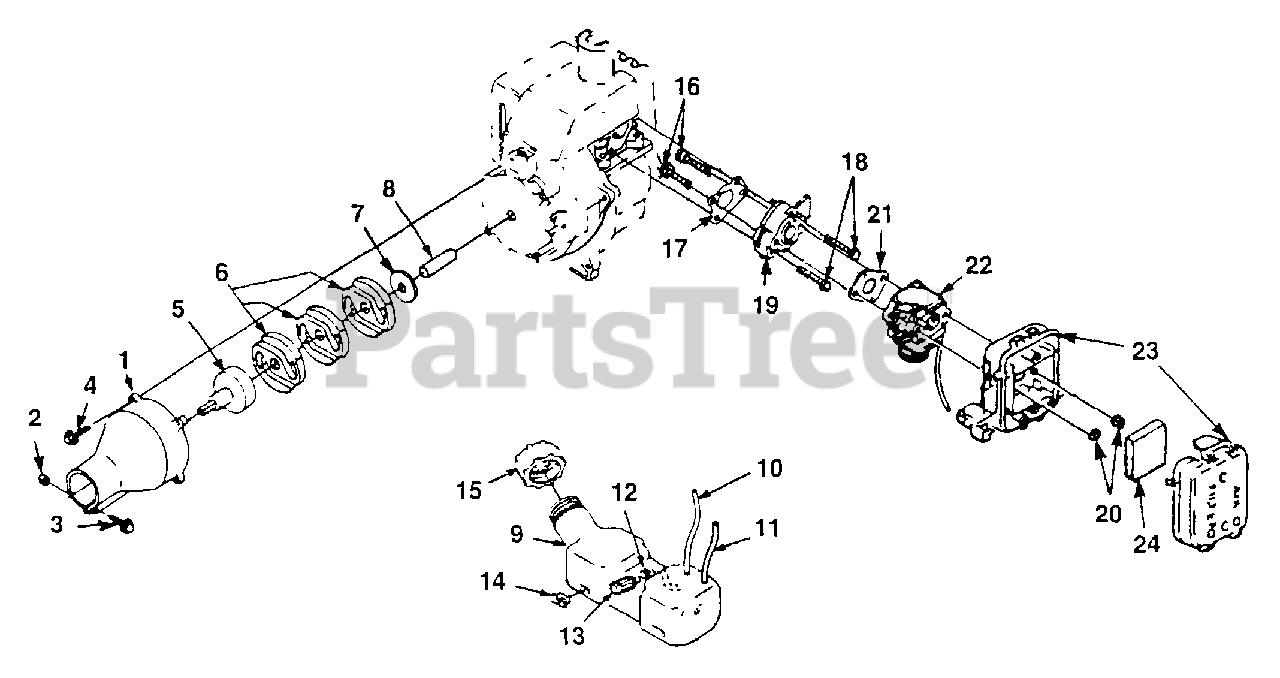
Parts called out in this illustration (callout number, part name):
1	TUBE ADAPTOR KIT
2	NUT-Hex (10-24)
3	SCREW-Sems Hex Hd (10-24 X 1 1/4")
4	SCREW-Sems Hex Hd (10-24 X 7/8")
5	DRUM & CONNECTOR
7	WASHER-Clutch
8	SPACER
9	FUEL TANK
10	TUBING-Rubber (4 1/4")
11	TUBING-Rubber (7 1/2")
12	CLAMP-Wire
13	FILTER-Fuel
14	BUMPER-Rubber
15	CAP-Fuel Tank
16	SCREW-Hex Hd (10-24 X 2 1/4")
17	GASKET-Heat Dam
18	SCREW-Taptite, Torx (10-24 X 1")
19	HEAT DAM
20	NUT-Hex (10-24)
21	GASKET-Carburetor
22	CARBURETOR (Walbro)
23	AIR FILTER KIT
24	FILTER-Air
